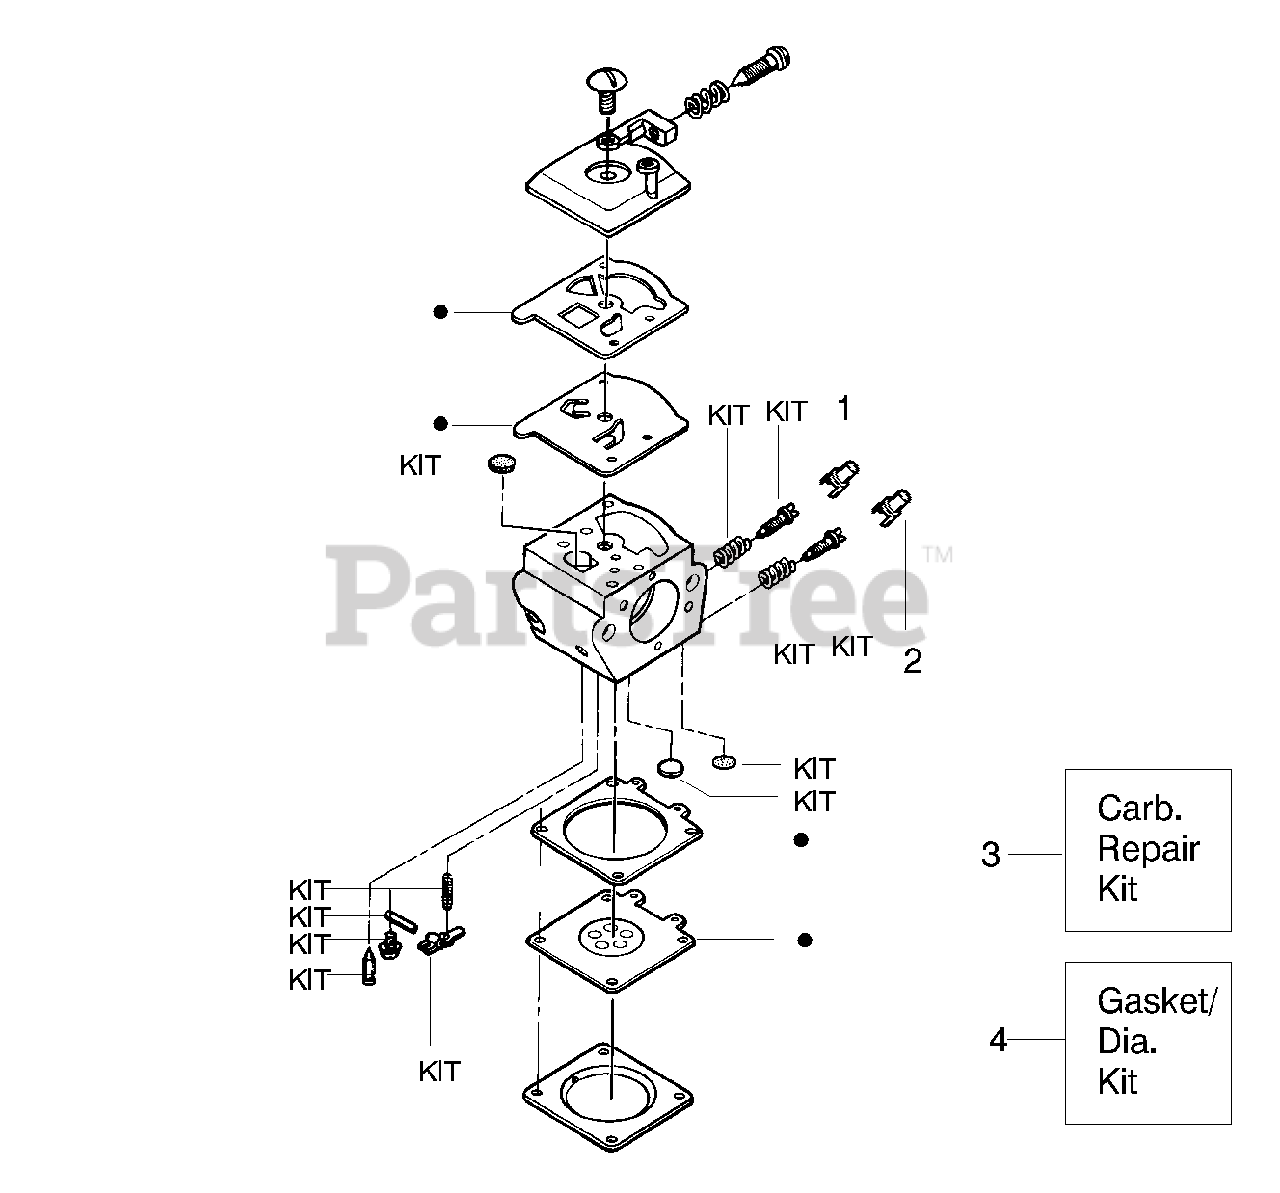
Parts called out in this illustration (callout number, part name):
1	Limiter Cap High (brown)
2	Limiter Cap Low (tan)
3	Carburetor Repair Kit Walbro (WT324)
4	Gasket Diaphragm Kit Walbro (WT324)
